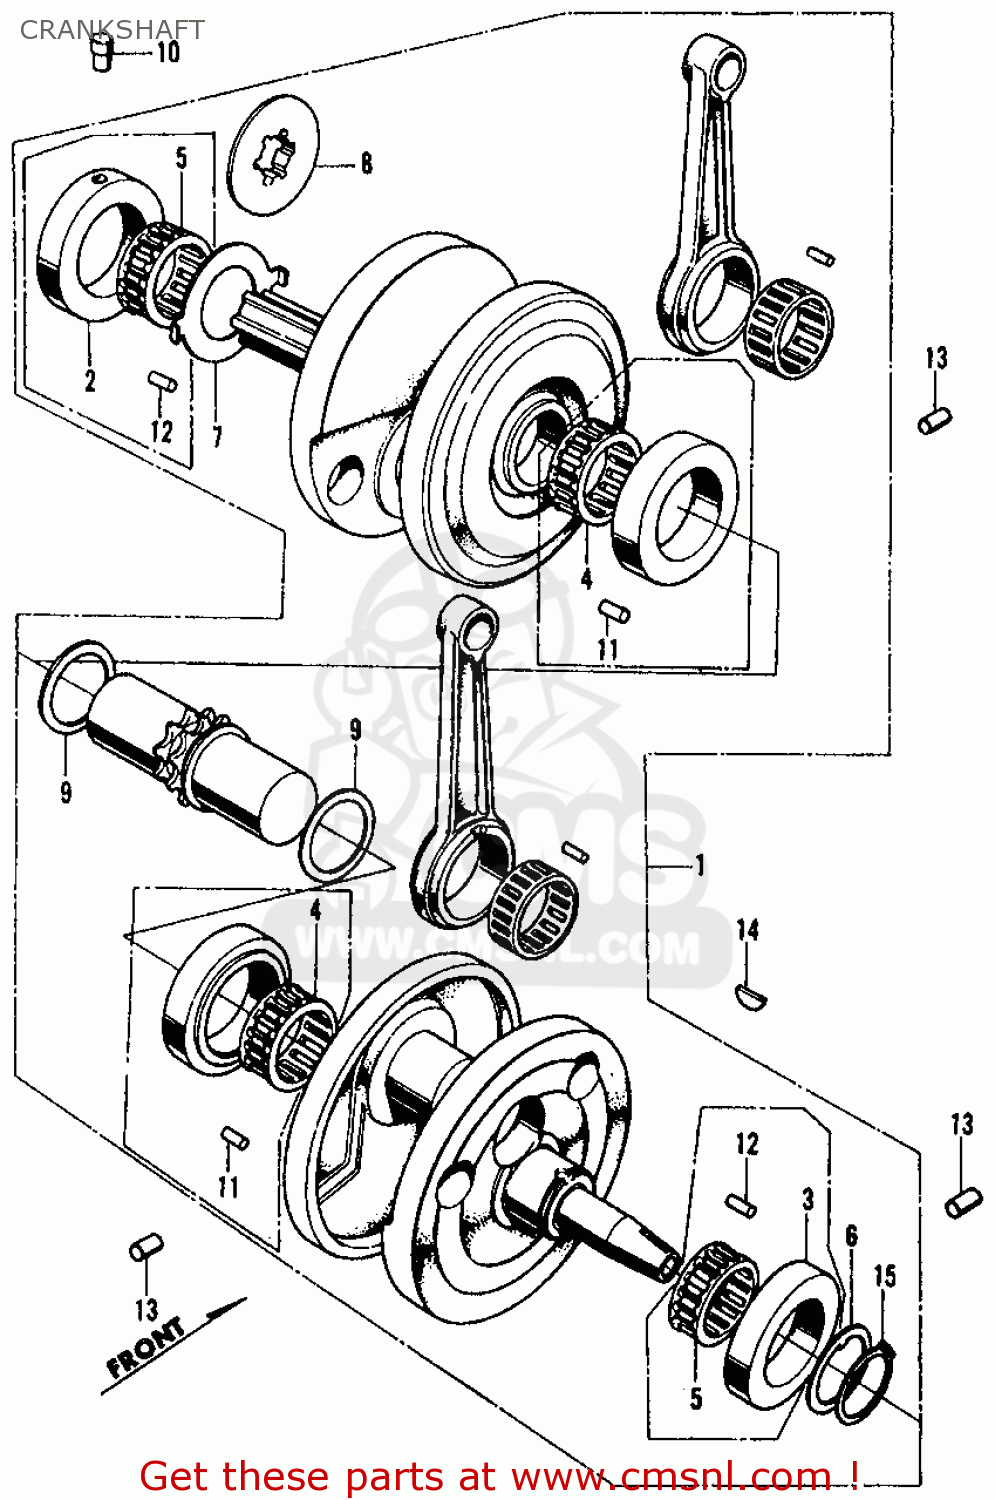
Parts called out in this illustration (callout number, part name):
1	CRANK SHAFT
2	OUTER RACE CASE
3	RACE BEARINGOUTER
4	RETAINER,BEARING
5	RETAINER,BEARING
6	WASHER B THRUST
7	WASHER THRUST 34
8	WASHER,THRUST 25
9	WASHER
10	PIN, R.
11	ROLLER,5X13
12	ROLLER 6X13
13	PIN,KNOCK 6X10B
14	KEY, WOODRUFF
15	CIRCLIP 34MM
